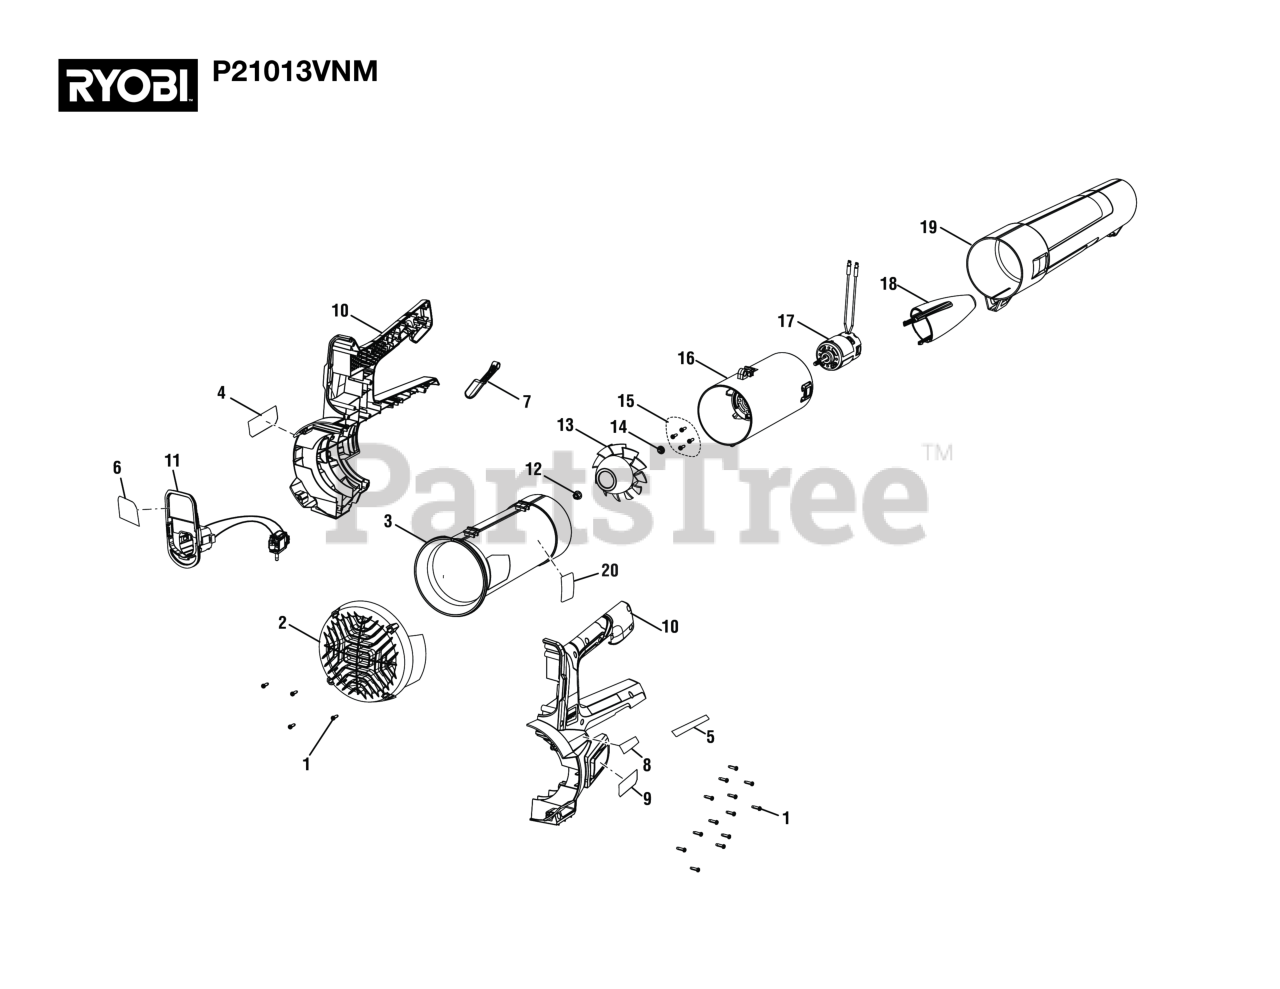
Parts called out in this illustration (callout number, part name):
1	Screw (M4 x 14 mm, T15 Torx Pan Hd.))
3	Inlet Bell Assembly
4	Motor Side Logo Label
5	Icon Label
6	Data Label
8	Warning Label
9	Warning Label (FR/ SP)
10	Housing Assembly
11	Switch and Battery Foot Assembly
12	Flange Lock Nut (M6 x 1 mm)
15	Screw w/Lock Washer (M5 x 8 mm, Pan Hd.)
18	Nose Cone
